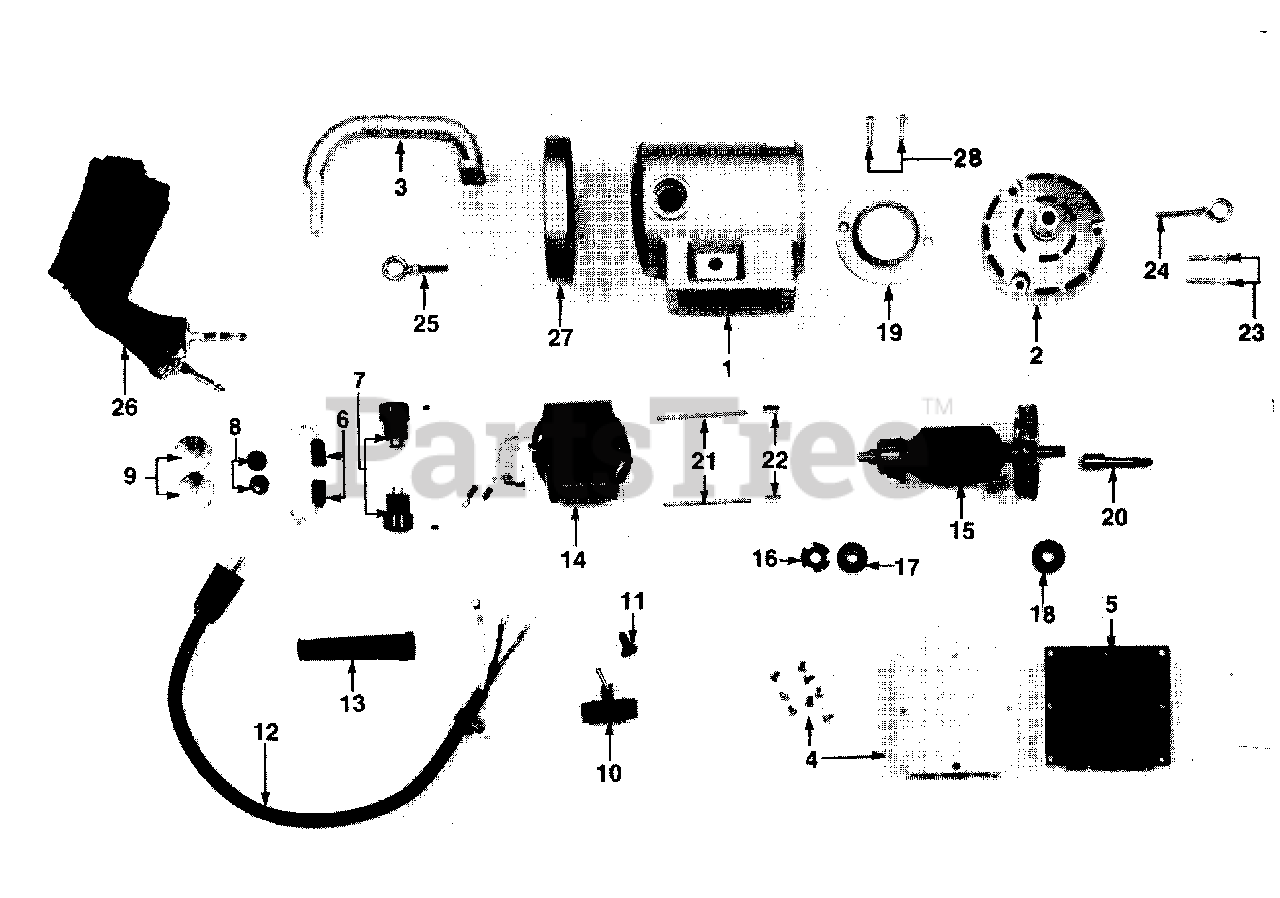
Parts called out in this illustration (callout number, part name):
1	HOUSING- Motor
2	END BELL
3	HANDLE- Motor
4	PLATE- Cover (w/screws)
5	GASKET- Cover plate
6	BRUSH- Motor
7	HOLDER- Brush
8	CAP- Brush holder
9	CAP- Metal
10	SWITCH- Electric
11	BOOT- Rubber switch
12	CORD- Switch
13	PROTECTOR- Rubber
14	COIL- Field
15	ARMATURE- w/fan
16	SPRING- Rear bearing thrust
17	BEARING- Rear
18	BEARING- Front
19	BAFFLE- Nylon vent
20	TIP- Motor drive
21	BOLT- Field coil (10-24 x 31/2") (2 required)
22	NUT- Field coil (10-24 x 5/8") (2 required)
23	BOLT- End bell (1/4-20 x 1 1/2") (2 required)
24	EYEBOLT- End bell (1/4-20 x 3")
25	EYEBOLT- Rear handle (1/4-20 x 21/2")
26	STRAP- Carrying
27	COVER- Rear motor
28	SCREW- Handle (2 required)
